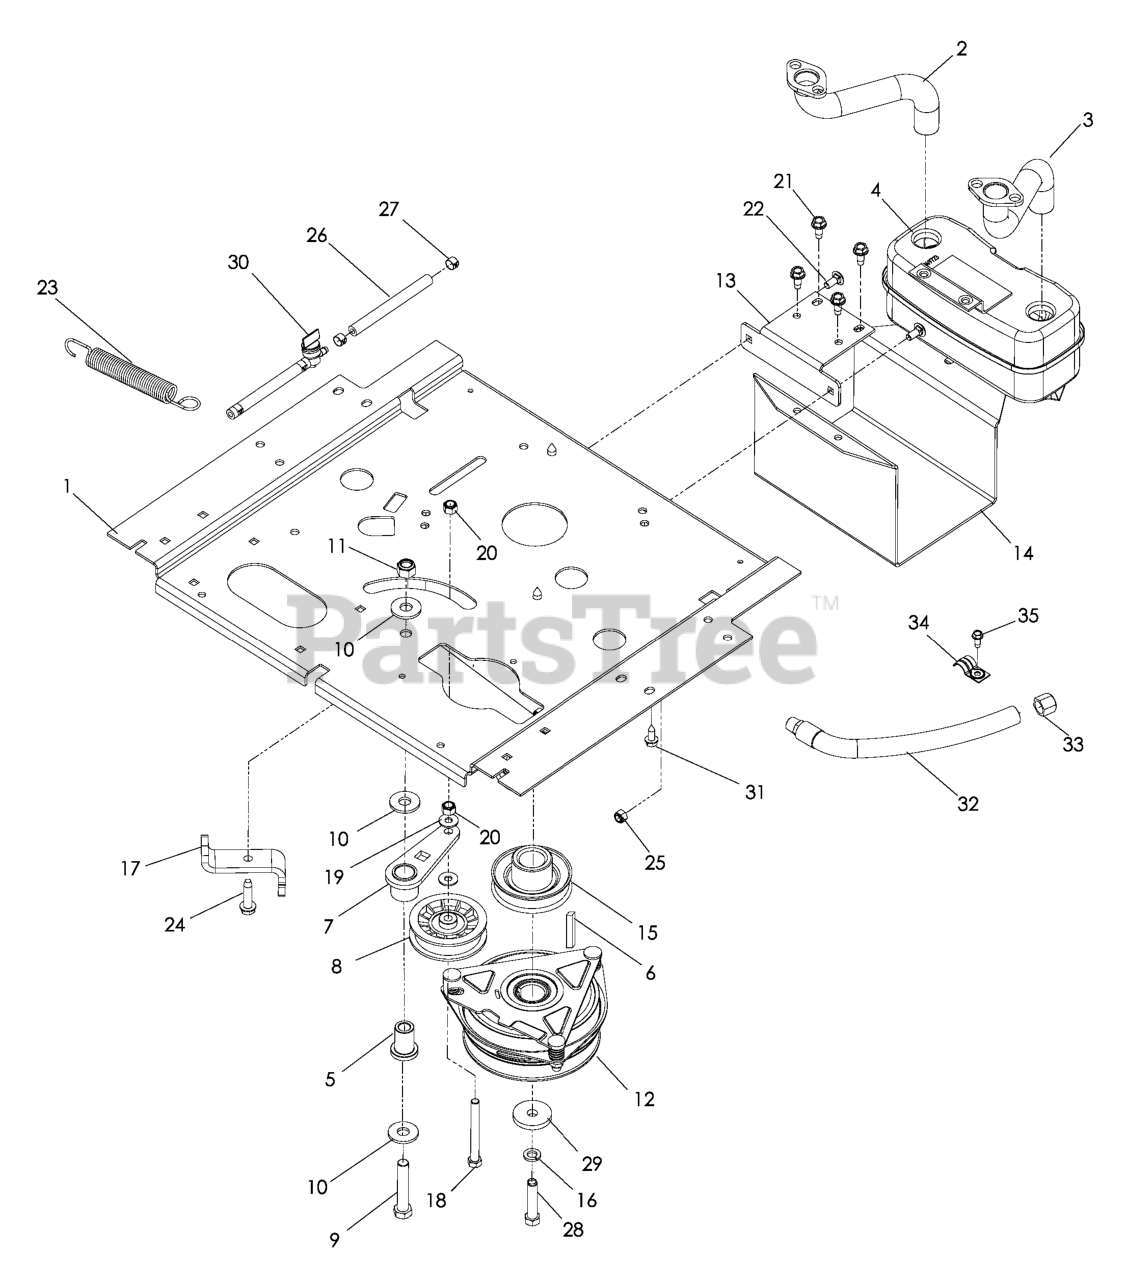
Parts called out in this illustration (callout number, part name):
1	PLATE, ENGINE, BLACK
2	RP.PIPE-EXHAUST LH
3	RP.PIPE-EXHAUST RH
4	MUFFLER ASM TWIN
5	PIVOT, IDLER
6	KEY 1/4 SQ X 2
7	RP.IDLER ARM WELDMENT
8	PULLEY, IDLER RAKE & ZTR
9	HCS 1/2C X 2 3/4
10	WASH USS FLAT 1/2
11	NUT 1/2-13 HEX NYLOC ZD
12	CLUTCH, 150 FT/LBS
13	BRACKET, MUFFLER, BLACK
14	GUARD, MUFFLER, BLACK
15	PULLEY, DRIVE
16	WASHER 7/16 LOCK
17	STOP, CLUTCH, OGURA, BLK
18	HCS 3/8-16X3 1/2 GR5
19	WASHER 5/16 FLAT
20	NUT 3/8-16 NYLOC
21	BOLT 5/16-18 X 3/4
22	BOLT 5/16C X 3/4" CARRIAGE
23	SPRING, DECK DRIVE
24	BOLT 3/8-16 X 1 1/2 ZINC CLEAR
25	5/16-18 NYLOC FLANGE NUT
26	FUEL LINE 5"
27	HOSE CLAMP
28	HCS 7/16-20 X 2 G8 ZN
29	SPINDLE WASHER
30	FUEL VALVE
31	HHFS 3/8-16 X 1.0 THD FORMING
32	OIL DRAIN HOSE
35	SCREW 1/4 X 5/8
